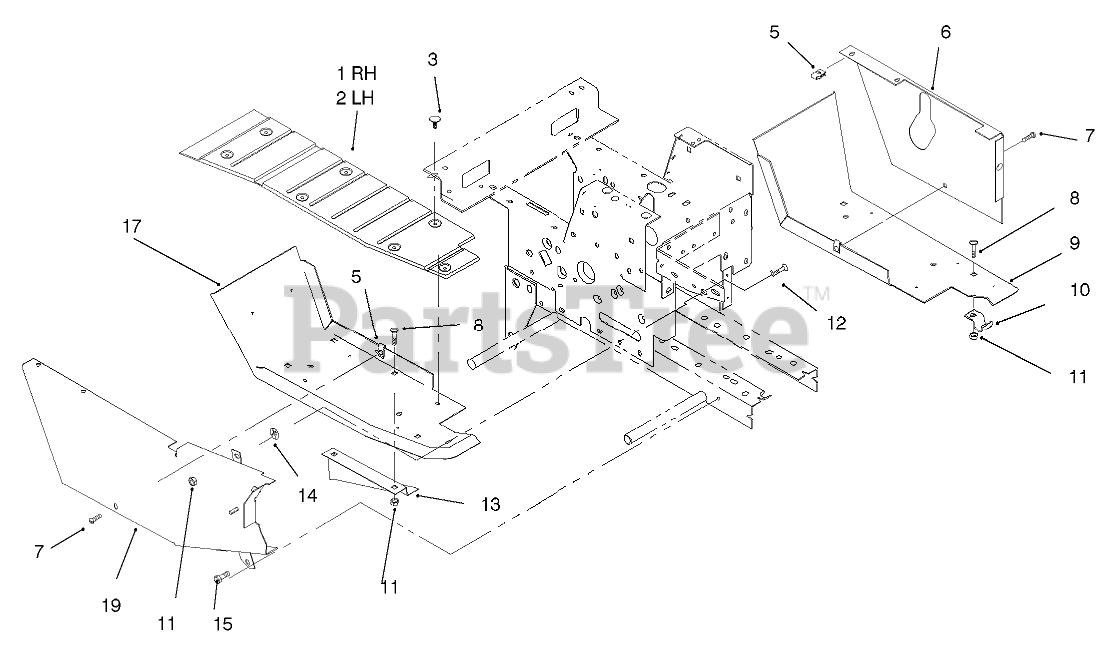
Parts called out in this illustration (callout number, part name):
1	PAD-FOOT RH
2	PAD-FOOT LH
3	FASTENER-PANEL
6	COVER-LH
7	SCREW-PPH
8	BOLT-CARR
9	PINION SHAFT
9	FOOTREST-LH
10	BRACKET
11	NUT-LOCK, NI
12	BOLT-CARR
13	GUIDE-LOWER BELT
14	NUT-PUSH
15	Bolt
17	FOOTREST-RH
18	Decal-Certification
19	SINGLE BELT GUARD ASM
